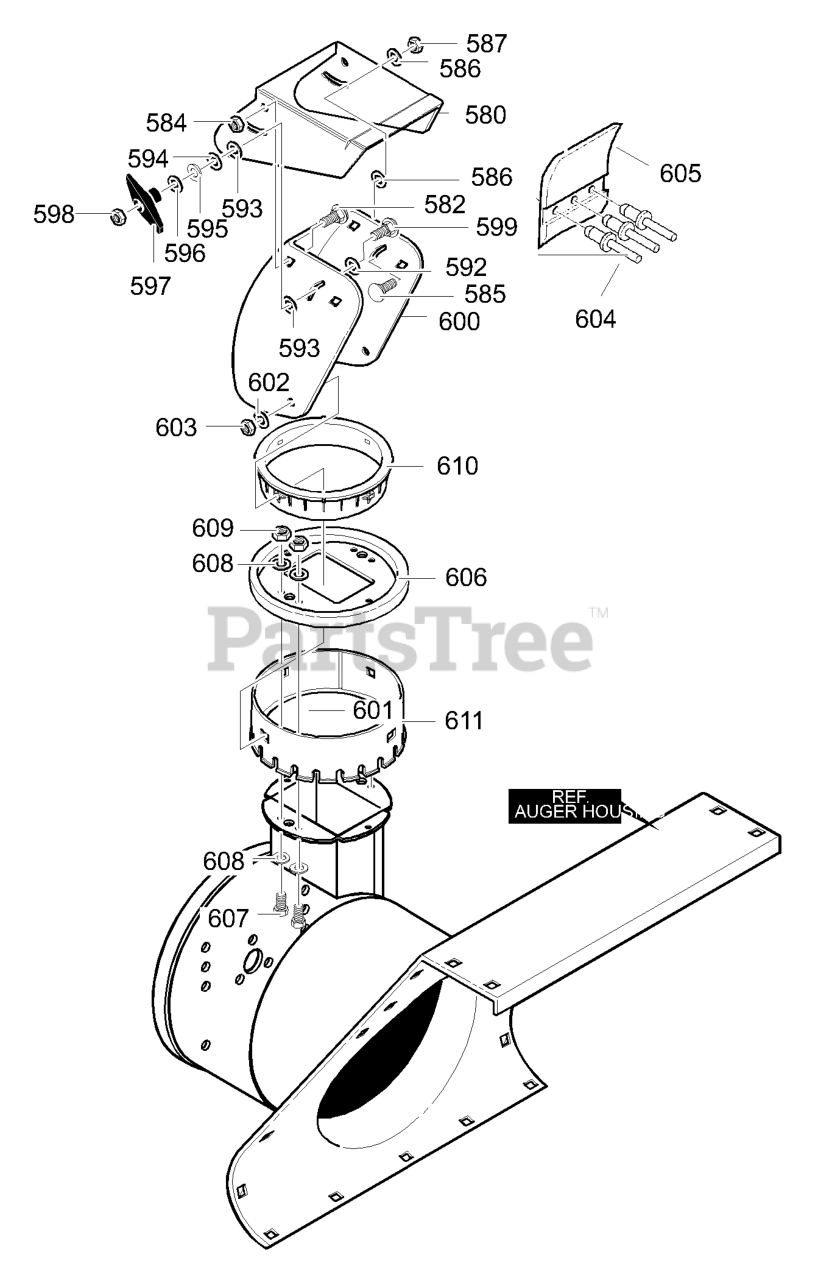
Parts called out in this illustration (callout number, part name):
580	ASSY., UPPER CHUTE
582	SCREW, 5/16-18 x 0.75
584	NUT, 5/16-18 HEX
585	SCREW, 5/16-18 x 0.75
586	WASHER
587	NUT, 5/16-18 HEX
592	WASHER
593	WASHER
594	WASHER, FLAT
595	WASHER
596	WASHER, FLAT
597	T-KNOB
598	NUT
600	LOWER CHUTE ASSEMBLY
601	BOLT, 5/16-18X1.00
602	FLATWASHER
603	NUT, 5/16-18
606	COLLAR, CHUTE
607	SCREW, 1/4-20X .75
608	FLATWASHER .281X .63X.065
609	NUT, 1/4-20 HEX
610	RETAINER, RING INNER
611	RETAINER, RING OUTER
